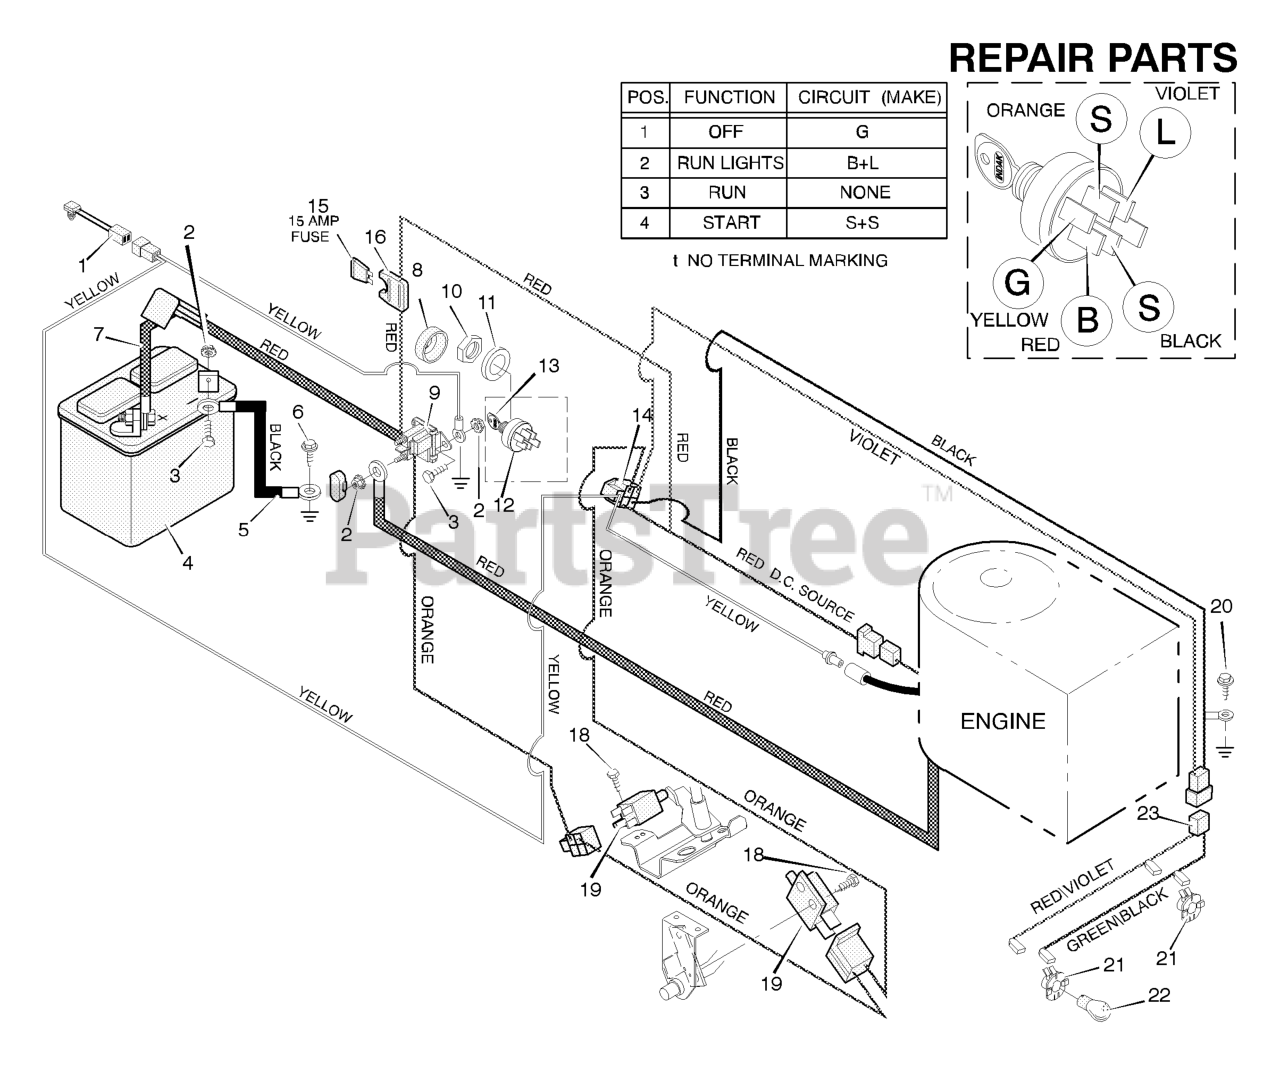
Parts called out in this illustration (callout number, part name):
1	Switch, Seat Sensor
2	Locknut
3	Bolt, Hex
4	Battery
5	Cable, Battery Ground
7	Cable, Red Battery
8	Cap, Ignition
9	Solenoid
10	Nut
12	Switch, Ignition
13	Key, Ignition
14	Harness, Chassis Wire
16	Holder, Fuse
19	Switch, Clutch
20	Screw
21	Socket, Light
22	Bulb, Light
23	Harness, Light Wire
24	Cover, Terminal
